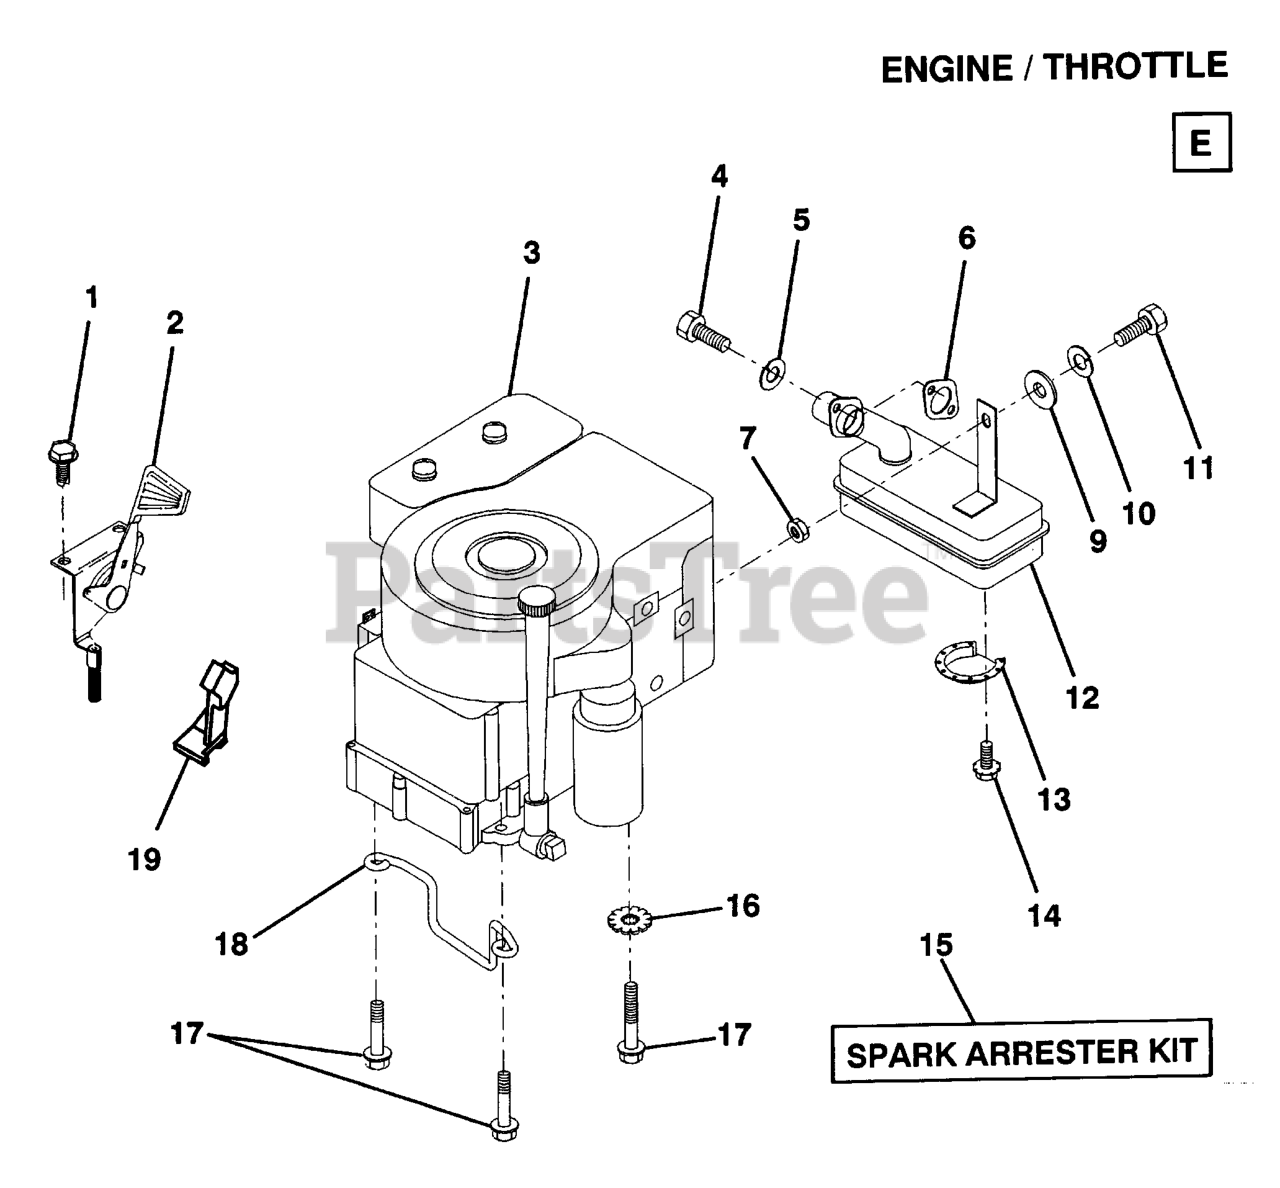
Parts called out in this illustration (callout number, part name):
1	BOLT.HEX.1/4.X.3/4.DICHROMATE
2	CONTROL.TH/CH.RH.BLK.FLG.EEC
4	BOLT
5	WASHER.LOCK.HVY.HLCL.SPR.5/16
6	GASKET ENGINE
7	LOCKNUT
9	WASHER
10	LOCKWASHER
11	Bolt Hex Fin 1/4-20 Unc x 1-1/2
12	MUFFLER
13	DEFL MUFFLER LTV
14	SCREW
15	SPARK ARREST
16	WASHER, LOCK 3/8
17	BOLT
18	KEEPER,DR BELT GR
19	THROTTLE STOP
